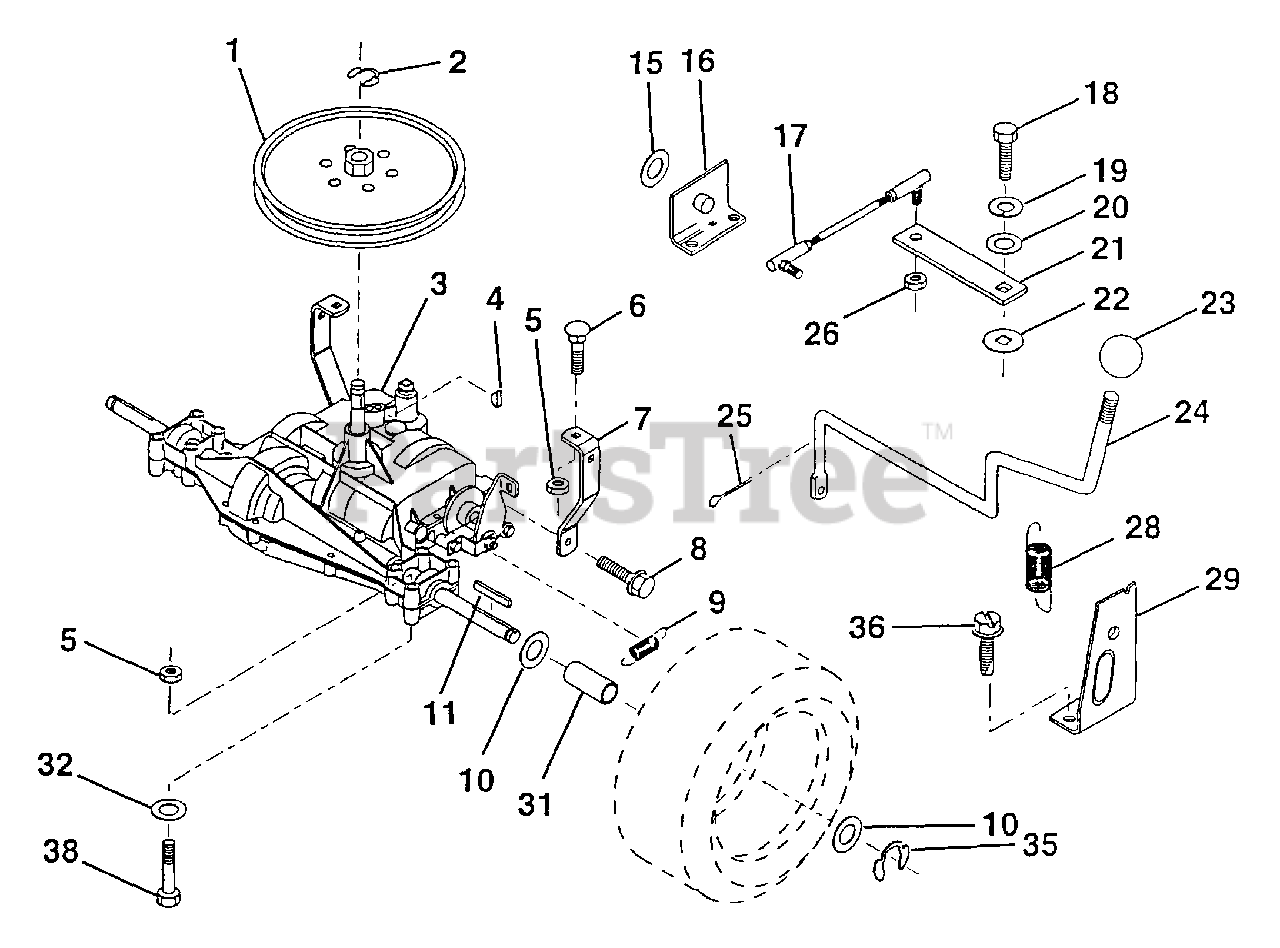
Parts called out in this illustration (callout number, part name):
1	Pulley
2	Ring, Retainer (AYP part number)
3	Transaxle
4	Key, Woodruff #9 (AYP part number)
5	Nut, Crownlock 5/16-18
6	Bolt, Carriage 5/16-18 UNC x 3/4
7	Strap, Torque
8	Screw 5/16-18 x 3/4
9	Spring, Brake
10	Washer 25/32 x 1-1/4 x 16 Ga.
11	Key, Square
15	Washer 17/32 x 1 x 16 Ga.
16	Support Handle Shift LH (AYP part number)
17	Link, Shift
18	Bolt 1/4-28 UNF Gr. 8 W/Patch
19	Washer, Lock 1/4
20	Washer 9/32 x 3/4 x 10 Ga.
21	Arm, Shift
22	Washer, Shift Plate
23	Knob, Duckhead
24	Rod Shift
25	Pin, Cotter 1/8 x 1
26	Locknut 5/16-24 UNF
28	Extension, Spring
29	Support Handle Shift RH
31	Spacer Axle
32	Washer 11/32 x 11/16 x 16
35	E-Ring
36	Screw, Thdrol 5/16-18 x 1/2
38	Bolt, Hex Hd 5/16-18 x 2-3/4
